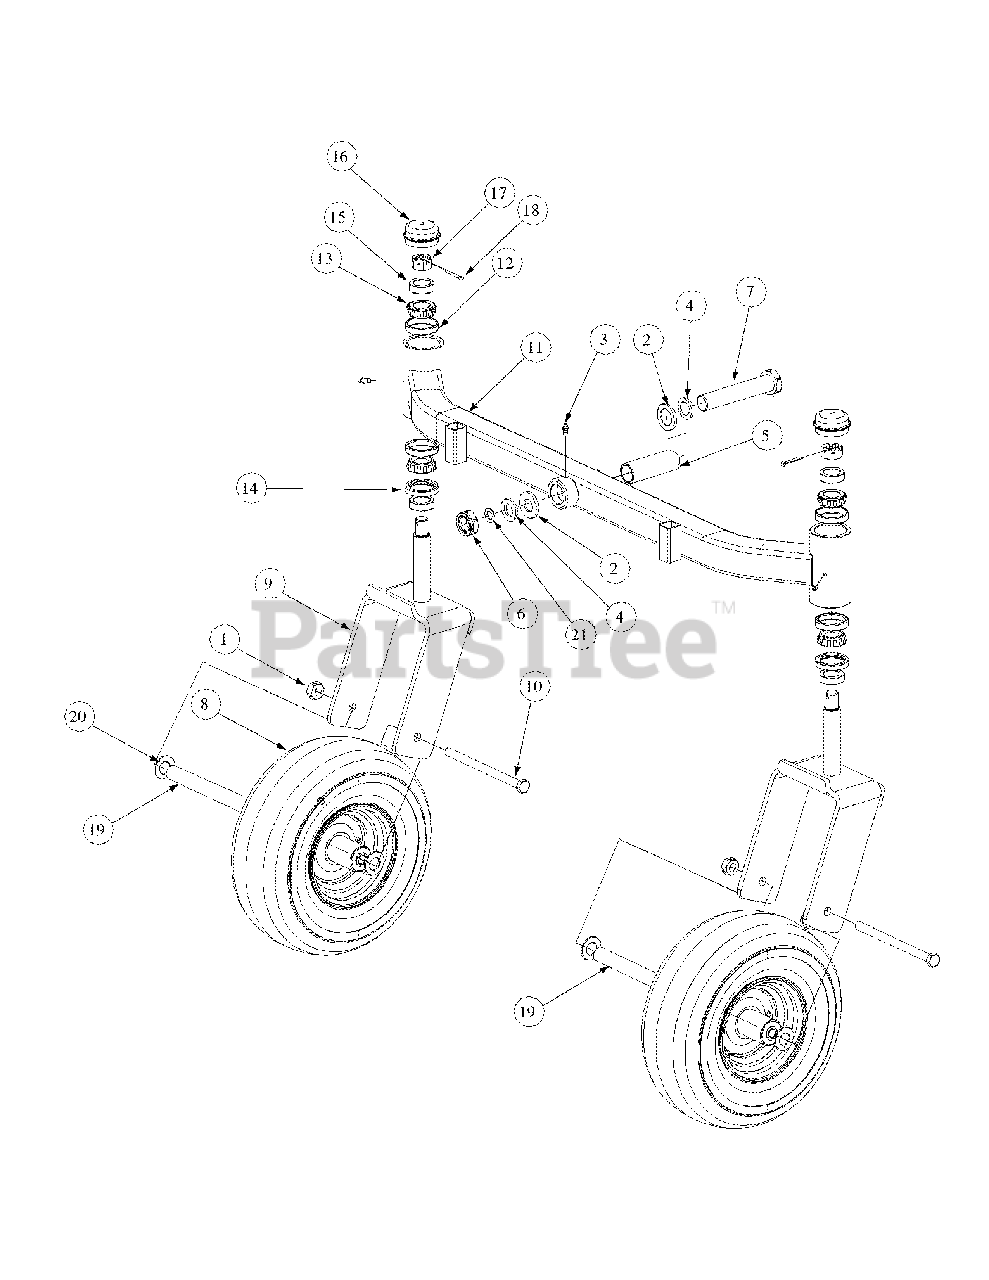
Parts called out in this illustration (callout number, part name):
1	Nut, 1/2-20, Center Lock
2	Bell Washer, 1.25 ID
3	Grease Fitting
4	Flat Washer, 1.00 ID
5	Spacer, 1.005 ID x 1.25 OD x 3.6
6	Nut, Jam, 1.0-14, Insert Lock
7	Hex Cap Screw, 1-14 x 5.0
8	Wheel Assembly, 13 x 6.50 x 6, White, includes:
9	Yoke, Caster Wheel
10	HHCS, 1/2-20, 7.50
11	Front Axle Assembly
12	Cup Bearing
13	Bearing Cone
14	Seal
15	Ring Seal
16	Grease Cap, 1.986 OD
17	Slotted Nut, 3/4-16
18	Cotter Pin, 5/32, 1.25
19	Wheel Spacer
20	Spacer, .812 ID x .218LG
21	Retainer Extension, Self Locking
